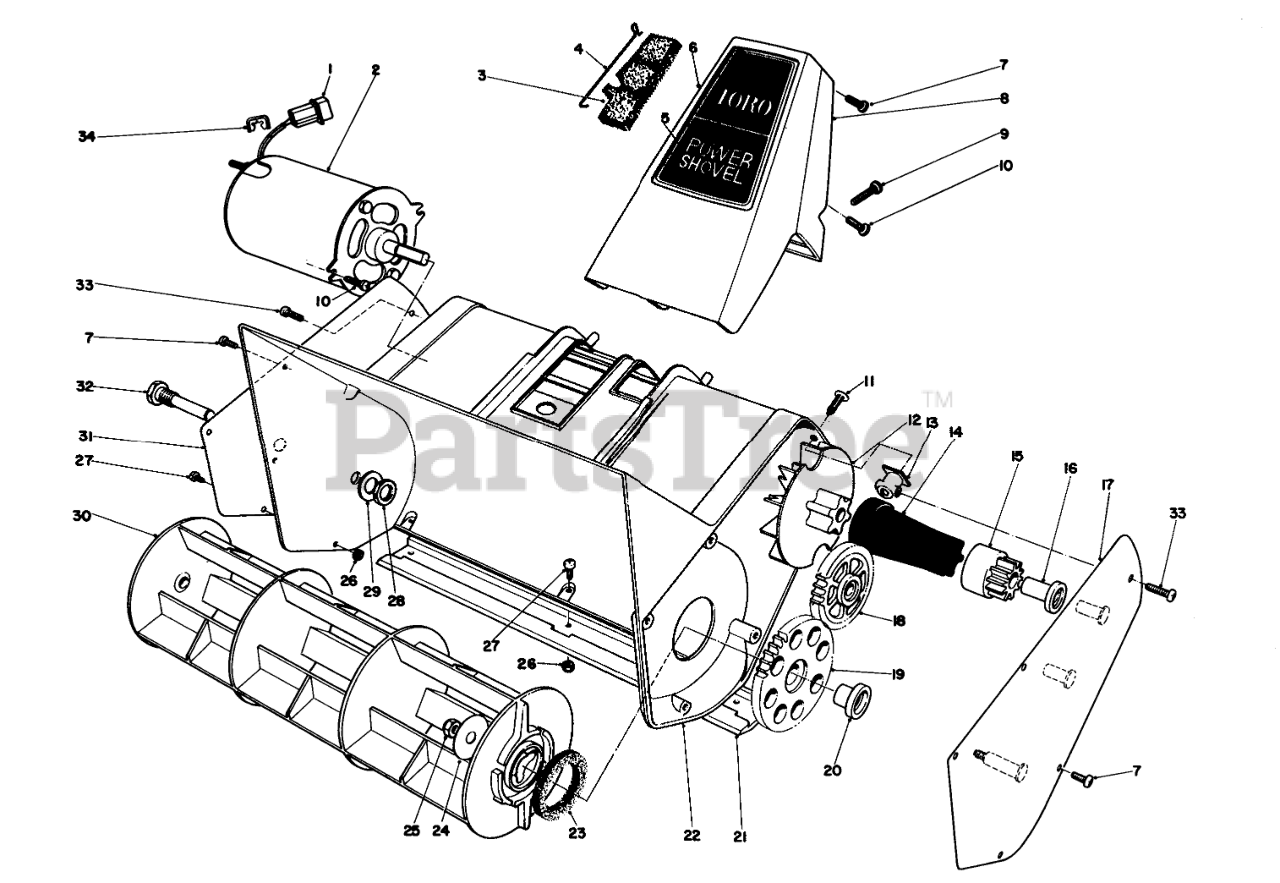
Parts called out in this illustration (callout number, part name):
1	Pin Housing
2	ELEC MOTOR
3	FOAM FILTER
4	RETAINER - FILTER
5	HANDLE SUPT DECAL
6	Handle Support-Front
7	SCREW-PPH
8	Handle Support-Back
9	SCREW-PPH
10	SCREW-PPH
11	XMAS TREE FASTENER
12	FAN, POWER SHOVEL
13	MTG BLOCK
14	DRIVE COUPLING
15	Drive Gear (Incl. Ref. #16)
16	BUSHING, DRIVE GEAR
17	Gear Carrier
18	Idler Gear
19	Rotor Gear Assembly (Incl. Ref. #20)
20	BUSHING, ROTOR GEAR
21	Scraper
22	Housing
23	FELT WASHER
24	ROTOR WASHER
25	NUT-LOCK, NI
26	NUT-LOCK
27	SCREW-PPH
28	3/8 24 JAM NUT
29	WASHER-FLAT
30	ROTOR
31	RT. SIDE COVER (RAW)
32	ROTOR PIN
33	Screw
34	Strain Relief
